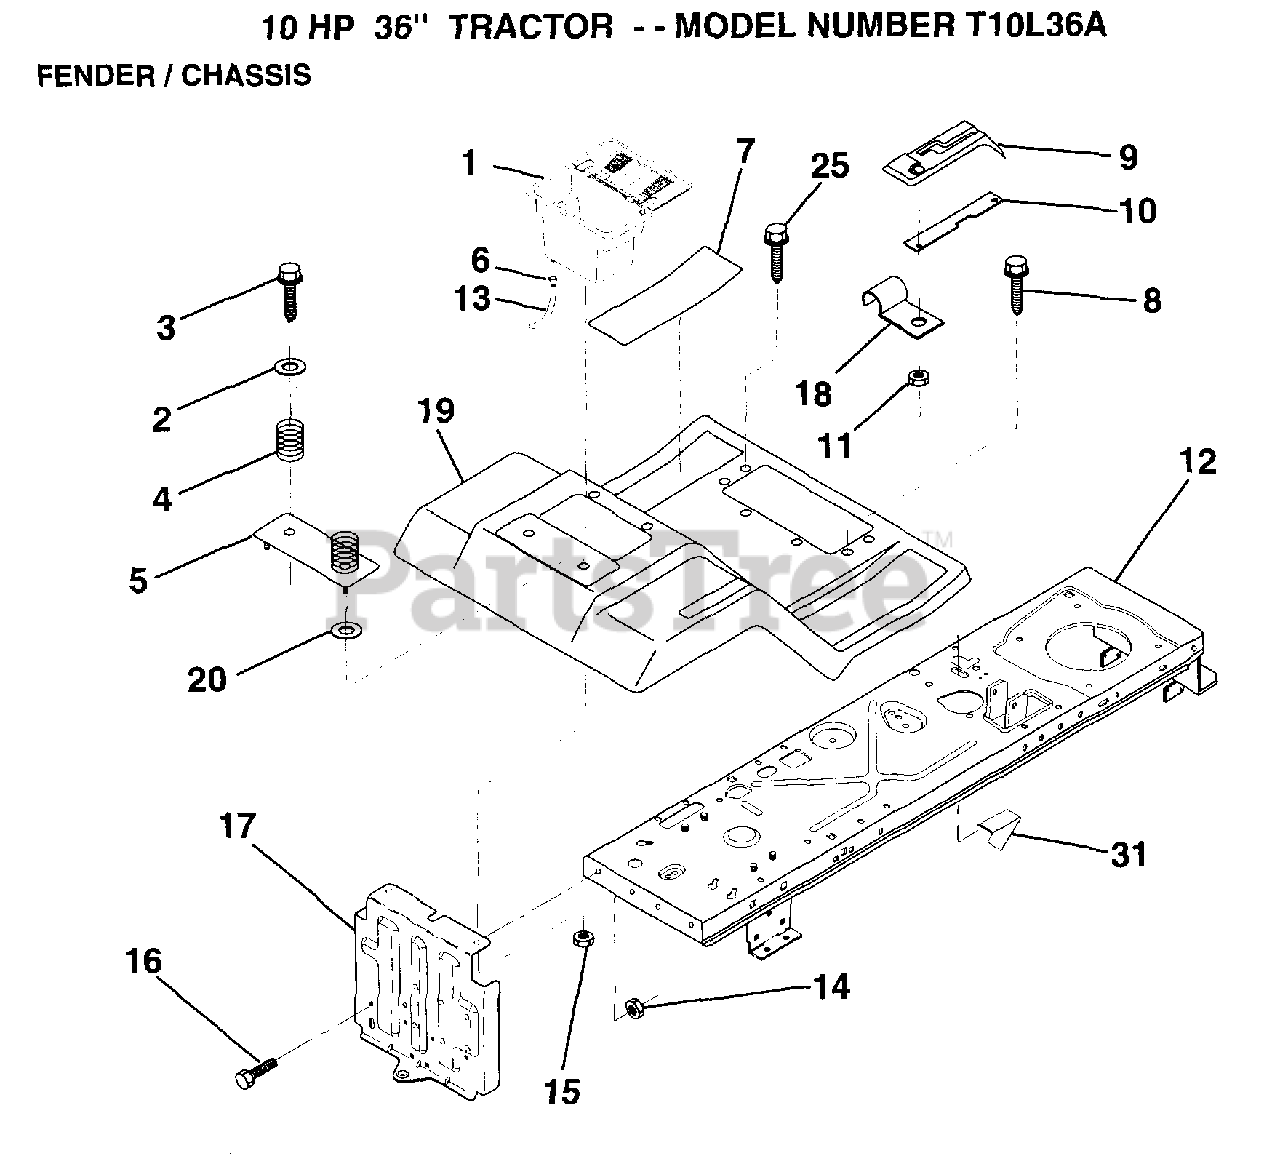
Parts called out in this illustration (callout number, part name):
2	WASHER
3	SCREW
4	SPRING COMPRESSIO
5	"PLATE, BATTERY"
6	HOSE CLAMP T
7	PAD FOOTREST
8	SCREW
9	CONSOLE SHFT 4SP
10	PLATE LOCK SHIFT
11	NUT
13	TUBE T
14	NUT
15	NUT
16	BOLT
17	DRAWBAR ASM LR
18	"CLIP,INSULATOR"
19	FENDER/FOOT MS419
25	SCREW TI
